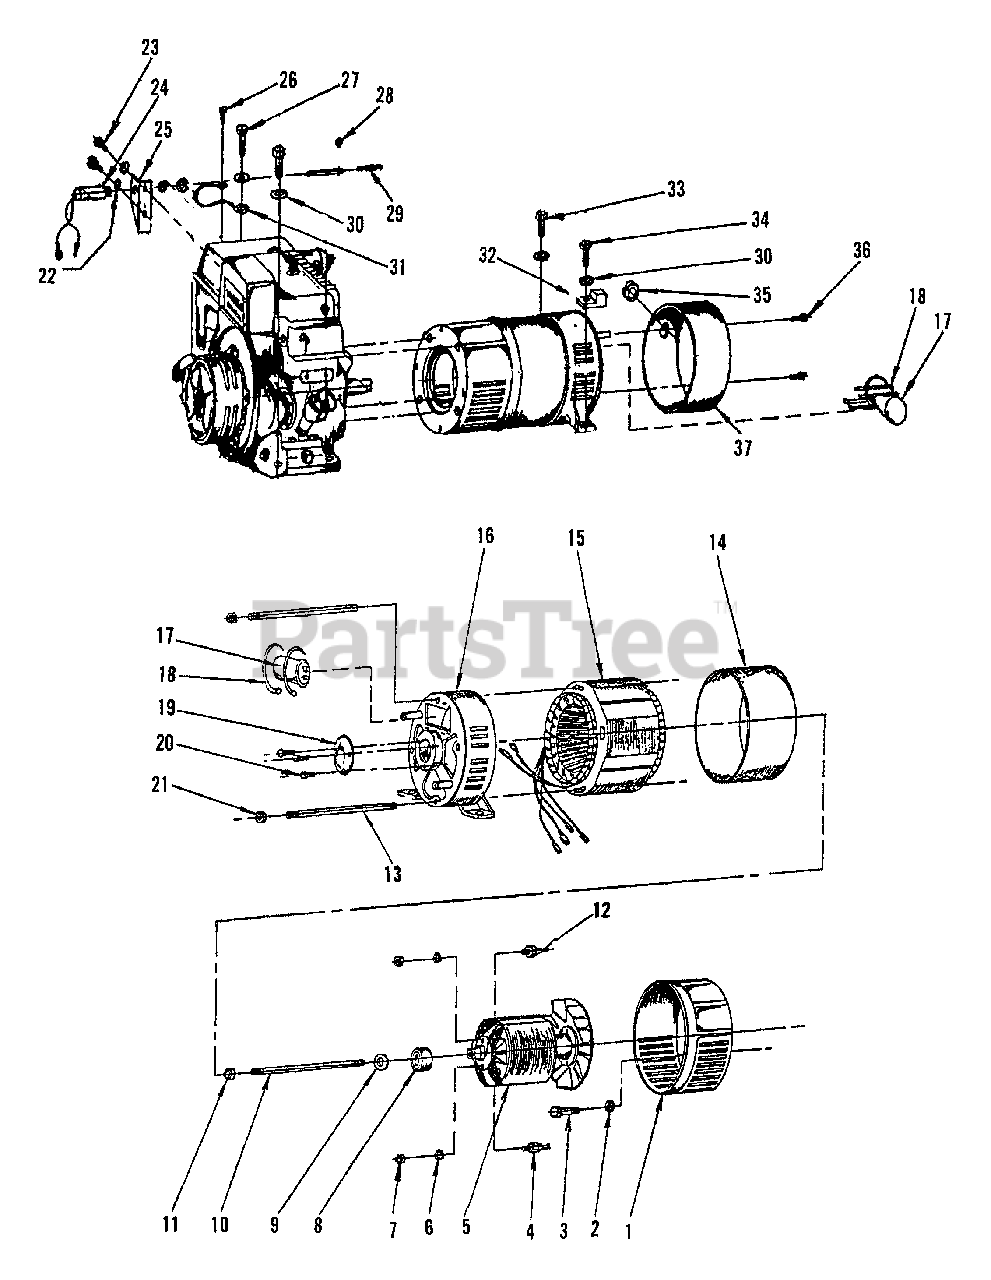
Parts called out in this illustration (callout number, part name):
1	DRIVE END ADAPTER CASTING
2	LOCKWASHER - 3/8"
3	SCREW - 3/8-16 X 1"
4	DIODE
5	ROTOR ASSY
6	LOCKWASHER, DIODE
7	NUT, DIODE
8	BEARING
9	LOCKWASHER - 5/16"
10	ROTOR THRU BOLT
11	NUT - 5/16-24 -- KEPS
12	DIODE
13	BOLT, STATOR
14	BAND, COVER
15	STATOR ASSY
16	CASTING, BEARING
17	CAPACITOR - 50UF 370V
18	TIE, CABLE
19	COVER, BEARING
20	SCREW - 10-24 X 1/2"
21	NUT - 1/4-20 -- KEPS
22	LOCKWASHER - 1/4"
23	BKT, MTG SCREW SOLENOID
24	SOLENOID ASSY
25	BRACKET, ECHO-MIZER
26	SCREW - 10-24
27	BOLT - 5/16-18 X 1-1/2"
28	PIN, SPLIT
29	SPRING, ECHO-MIZER
30	LOCKWASHER - 5/16"
31	LEAD - GROUND
32	LUG, GROUND - 1/0-14 CU/AL
33	5/16-18X5/8 HHS
34	5/16-18X7/8 HHS
35	GROMMET
36	SCREW - 10-24
37	COVER, END
